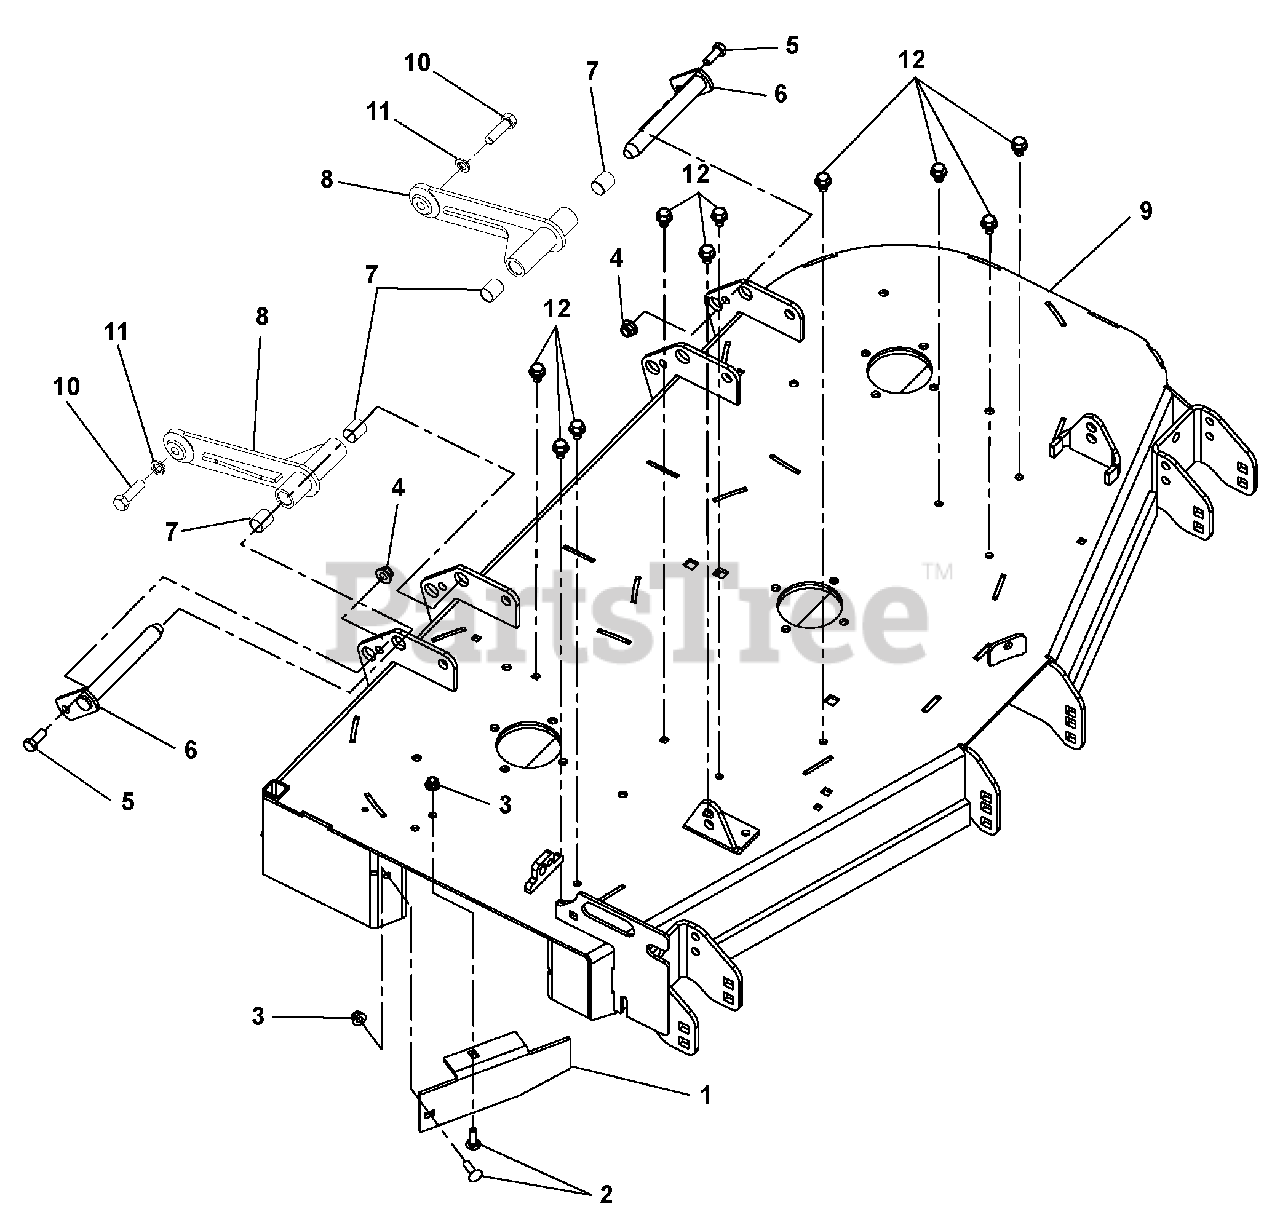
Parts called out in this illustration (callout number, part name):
1	44"-48" REAR DISCH BAFFLE -RED
2	BLT-RDHDSQNK .31-18X1.00 G5YZ
3	NUT-LK-NYL-FLG .31-18 YWZC
4	NUT-LK-NYL-FLG .38-16 YWZC
5	BLT-HEX .38-16X1.00 GR5 YWZC
6	WELDMENT, MOWER MTG. PIN
7	BRG, .750 X .875 X 1.000
8	DECK PUSHER ARM WMT - BLACK
9	48" 100I SIDE DISCH DECK - RED
10	BLT-HEX .50-13X1.75 GR5 YWZC
11	WSHR-LK .50X.125 REG YWZC
12	SCR-TAP .38-16X.50 HWH TR YWZ
